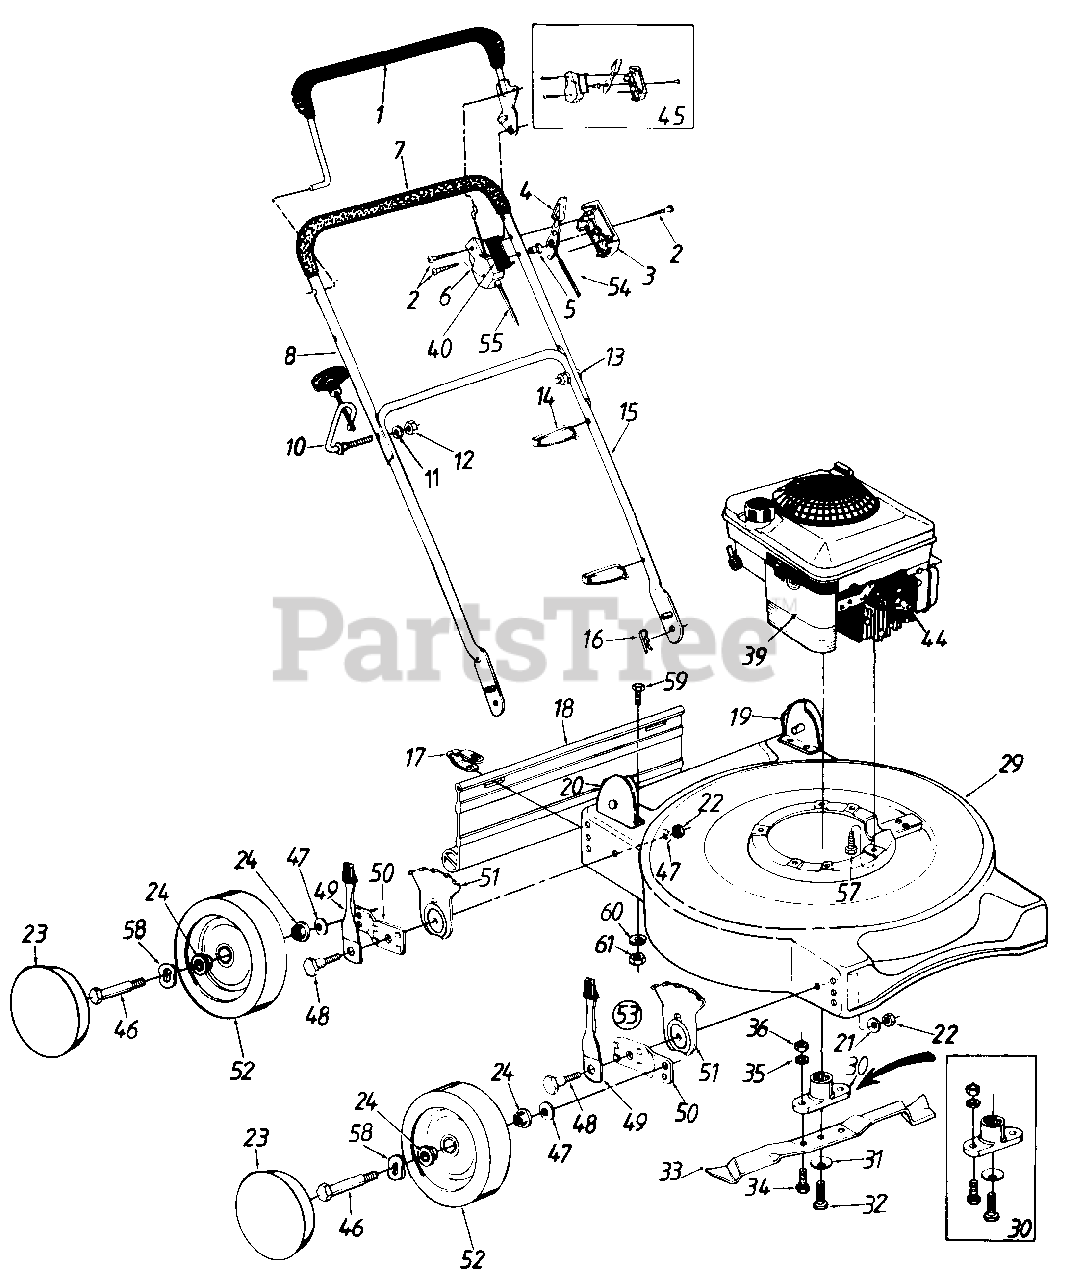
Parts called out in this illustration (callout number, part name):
2	SCREW-TRUSS MACH
3	PANEL HALF-CONTROL
4	LEVER-THROTTLE CONT-REV
5	PIN-CONTROL DISC
6	PANEL HALF-CLUTCH
7	GRIP-FOAM
8	HANDLE-UPPER
10	SCREW-RECOIL HANDLE GUIDE
11	WASHER-LOCK-5/16
12	NUT-HEX 5/16-18
13	BOLT-CARRIAGE-CURV 5/16-18 X 1.38
14	TIE-CABLE
15	LOWER HANDLE
16	PIN-INTERN COT-5/16 DIA
17	CLIP-HINGE
19	BRACKET ASSY-HDLE-RH
20	BRACKET ASSY-HDLE-LH
21	WASHER-BELL .390 ID X 1.375 X .062
22	NUT-HEX 3/8-16
23	HUB CAP
24	BEARING-BALL
29	DECK ASSEMBLY-20IN MULCHING
30	KIT-BLADE ADAPTER-SPLINED
31	WASHER-BELL
32	SCREW-HEX 7/16-20 X 1.50
33	BLADE-20IN-MULCHING
34	SCREW-HEX 3/8-24 X 1 LG
35	WASHER-LOCK-3/8
36	NUT-HEX 3/8-24
44	INSULATOR-SPARK PLUG
45	KIT-THROTTLE CONTROL
46	SCREW-SHLD .498 DIA X 1.450
47	WASHER-BELL .400 ID X .88 X .060
48	SCREW-SHLD R
49	LEVER & KNOB ASSY
51	PLATE-HGT ADJ
52	WHEEL ASSY W/TIRE
53	ADJUSTER ASSY-HGT-RH
54	WIRE-THROTTLE-52 IN
55	CABLE-CONTROL
57	SCREW-HEX R
58	WASHER-WAVE .530 X .780 X .013
59	SCREW-HEX 1/4-28 X .75
60	LOCK WASHER 1/4 DIA
61	NUT-HEX 1/4-28
